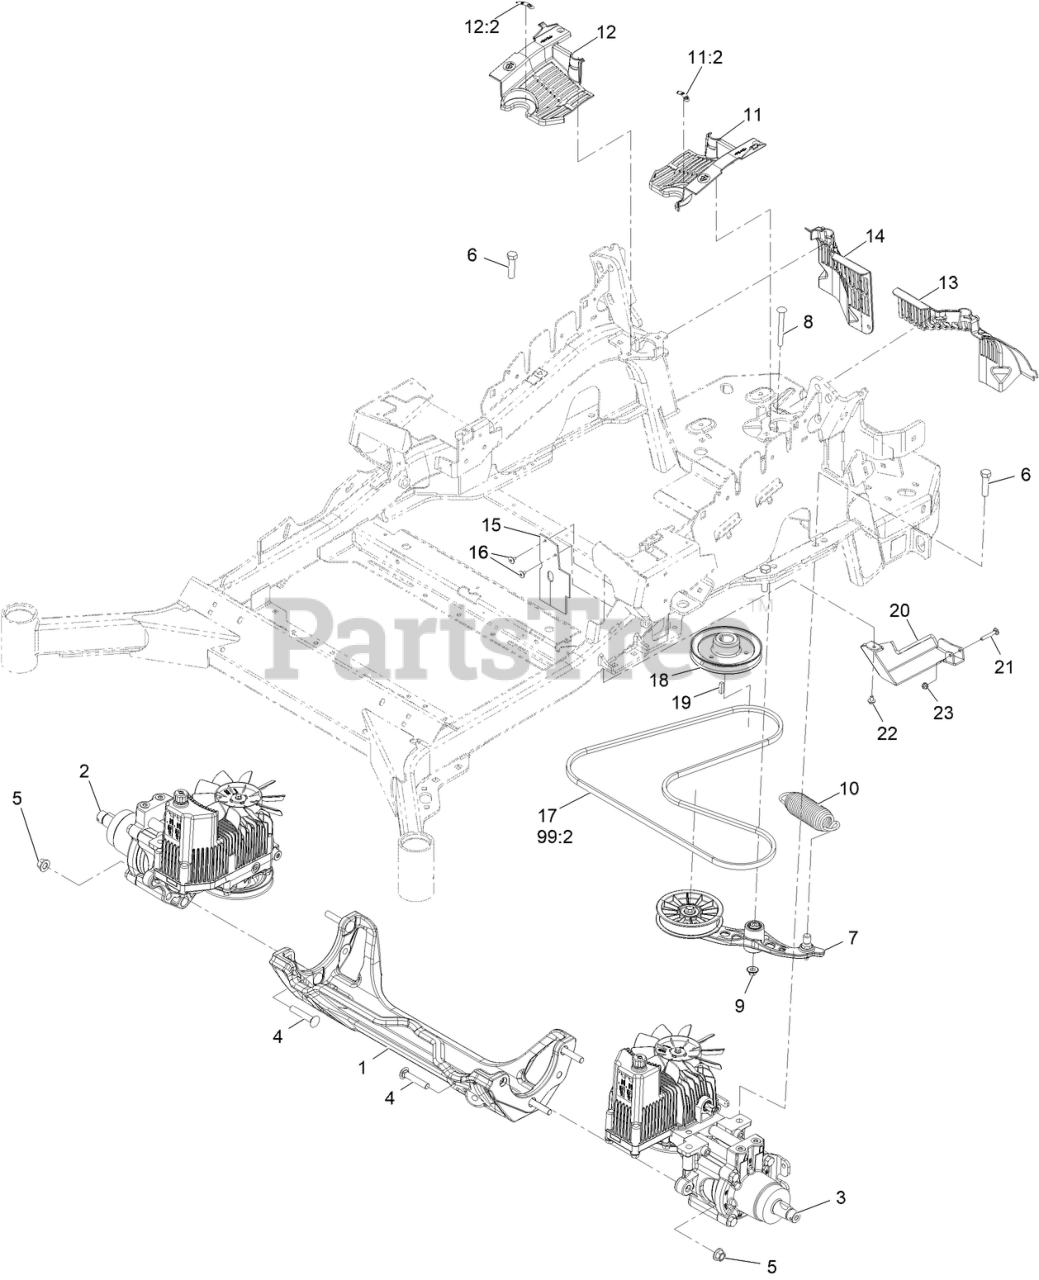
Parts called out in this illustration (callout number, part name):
1	CRADLE-HYDRO
2	Hydro-RH
3	Hydro-LH
4	SCREW-CARR
5	Nut-Lock 1/2-13
6	SCREW-HH
7	PUMP IDLER ASM
8	BOLT-SHOULDER, CARRIAGE 3/8-16 X 3 1/2
9	Nut-Nyloc 3/8-16 Flg
10	SPRING-EXTENSION
11	LH HYDRO GUARD ASM
11:2	DECAL-OIL, HYDRO
12	RH HYDRO GUARD ASM
12:2	DECAL-OIL, HYDRO
13	GUARD-HYDRO REAR, LH TRIM
14	GUARD-HYDRO, REAR (RH)
15	DEFLECTOR-AIR FLOW
16	RIVET-POP
18	SHEAVE, W/HUB
20	TANK GUARD WLDMNT
21	SCREW-CARR
22	SCREW AND WASHER ASM
